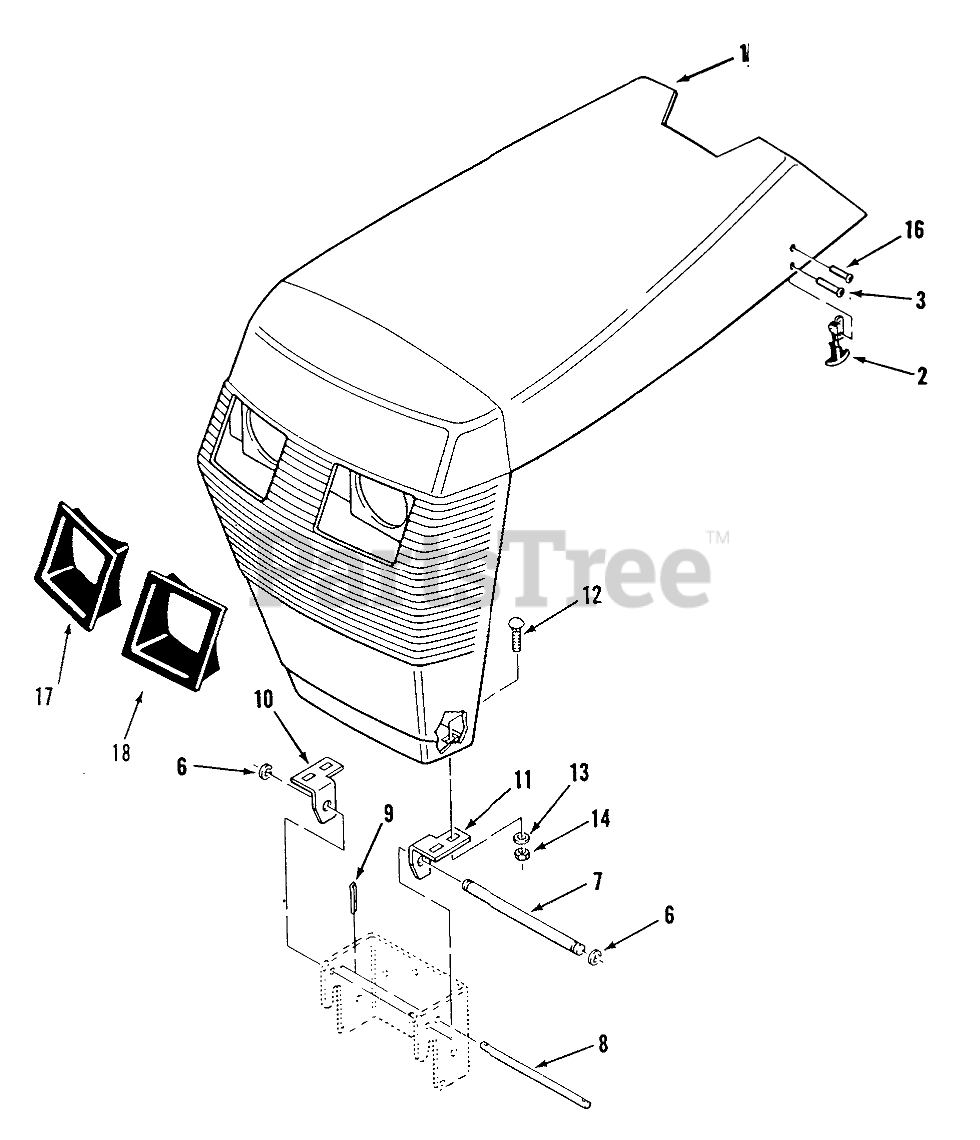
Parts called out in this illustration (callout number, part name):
1	Hood 516, 518 & 520-HC
2	Hood Latch (includes 109236 Handle Ass-y & 109237 Latch Keeper)
3	RIVET -4
6	RING-RETAINING
7	GRILL PIVOT ROD
8	ROD-HOOD STOP
9	Cotter Pin
10	BRKT-GRILL PIVOT R
11	BRKT-GRILL PIVOT R (NS)
12	Bolt-Carriage
14	Nut
16	RIVET
17	BEZEL-HEADLIGHT, RH
18	BEZEL-HEADLIGHT, LH
24	WASHER 5/16 SAE
